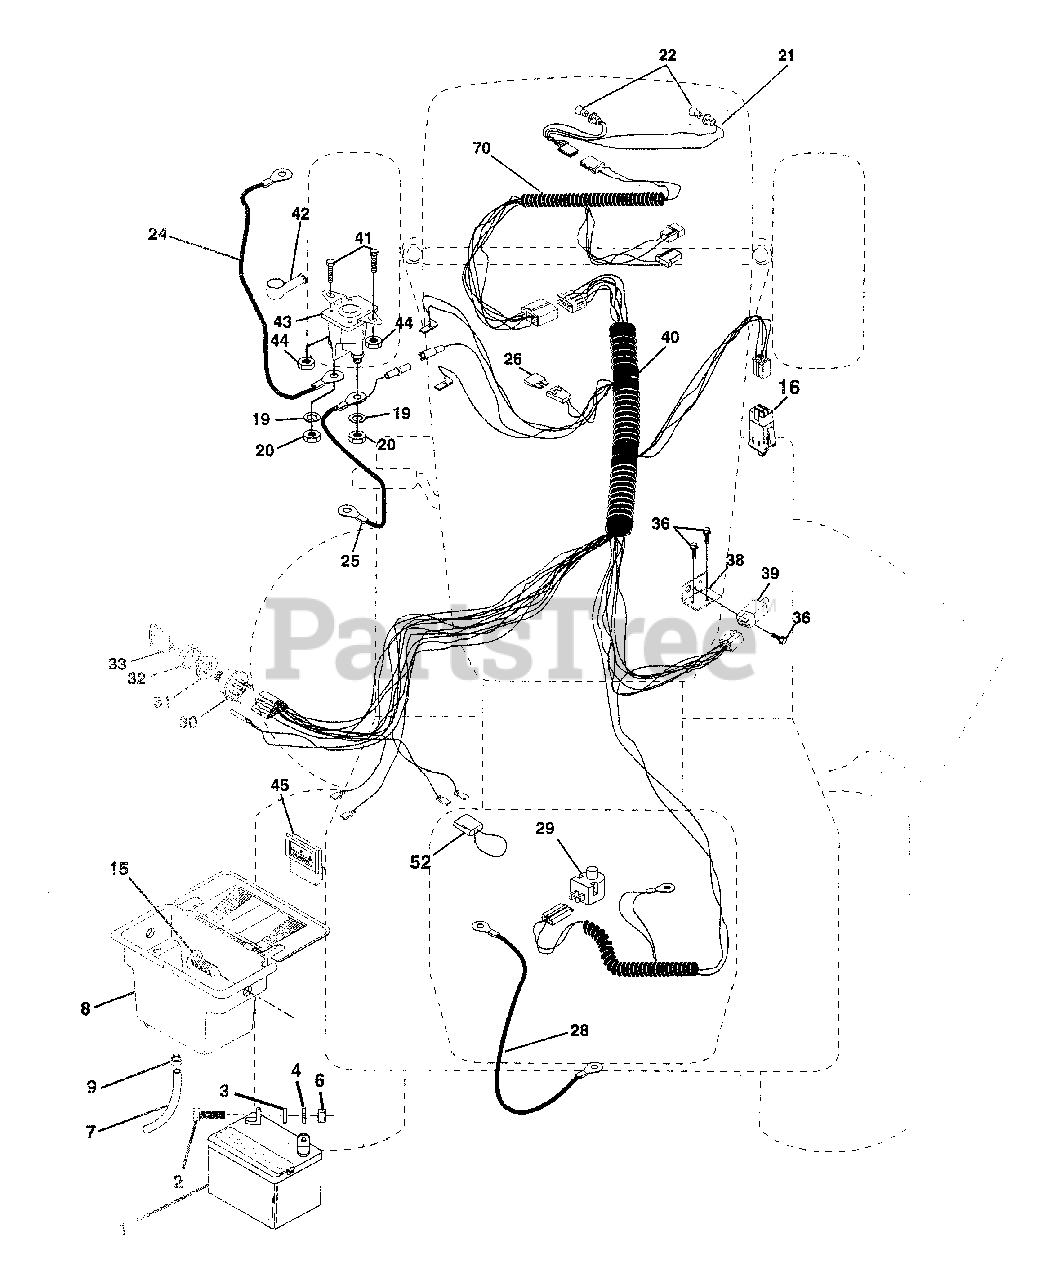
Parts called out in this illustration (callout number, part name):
1	Battery 12 Volt 25 AMP
2	Bolt Hex Hd 1/4-20unc X 3/4
3	Washer 9/32 X 5/8 X 16 Ga.
4	Washer Lock Hvy Helical 1/4
6	Nut Fin Hex 1/4-20 Unc
7	Tube Plastic 12"
8	Case Battery Hng Mech W/lid W/ Holes W.Brty
9	Clamp Hose Olive
15	Fastner, Snap-In
16	Switch Interlock Push-In
19	Washer Lock 1/4
20	Nut Jam Hex 1/4-20 Unc
21	Harness Asm Light W/4152j
22	Bulb Light #1156
24	Cable Battery 6 Ga 11" red
25	Cable Battery 6 Ga red w/16 wire
26	Fuse 30 AMP Auto Green
28	Cable Ground 6 Ga 12" black
29	Switch Plunger Nc Gray
30	Switch Ign 4 pos w/lights
31	Nut Ignition
32	Cover Sw Ignition
33	Key Ign Modleded Generic
36	Screw Tap Hex #10-24unc X 1/2
38	Bracket, Switch, Interlock
39	Switch Intlk Clutch Red 4 Term
40	Harness Ign Hm LT PL Mech
41	Bolt Blk Fin Hex 1/4 - 20 x 1/2 UNC
42	Cover Terminal Red
43	Solenoid
44	Nut Keps Hex 1/4-20 Unc
45	Ammeter Rectangular
52	Protection Wire Loop
70	Harness, Eng.
